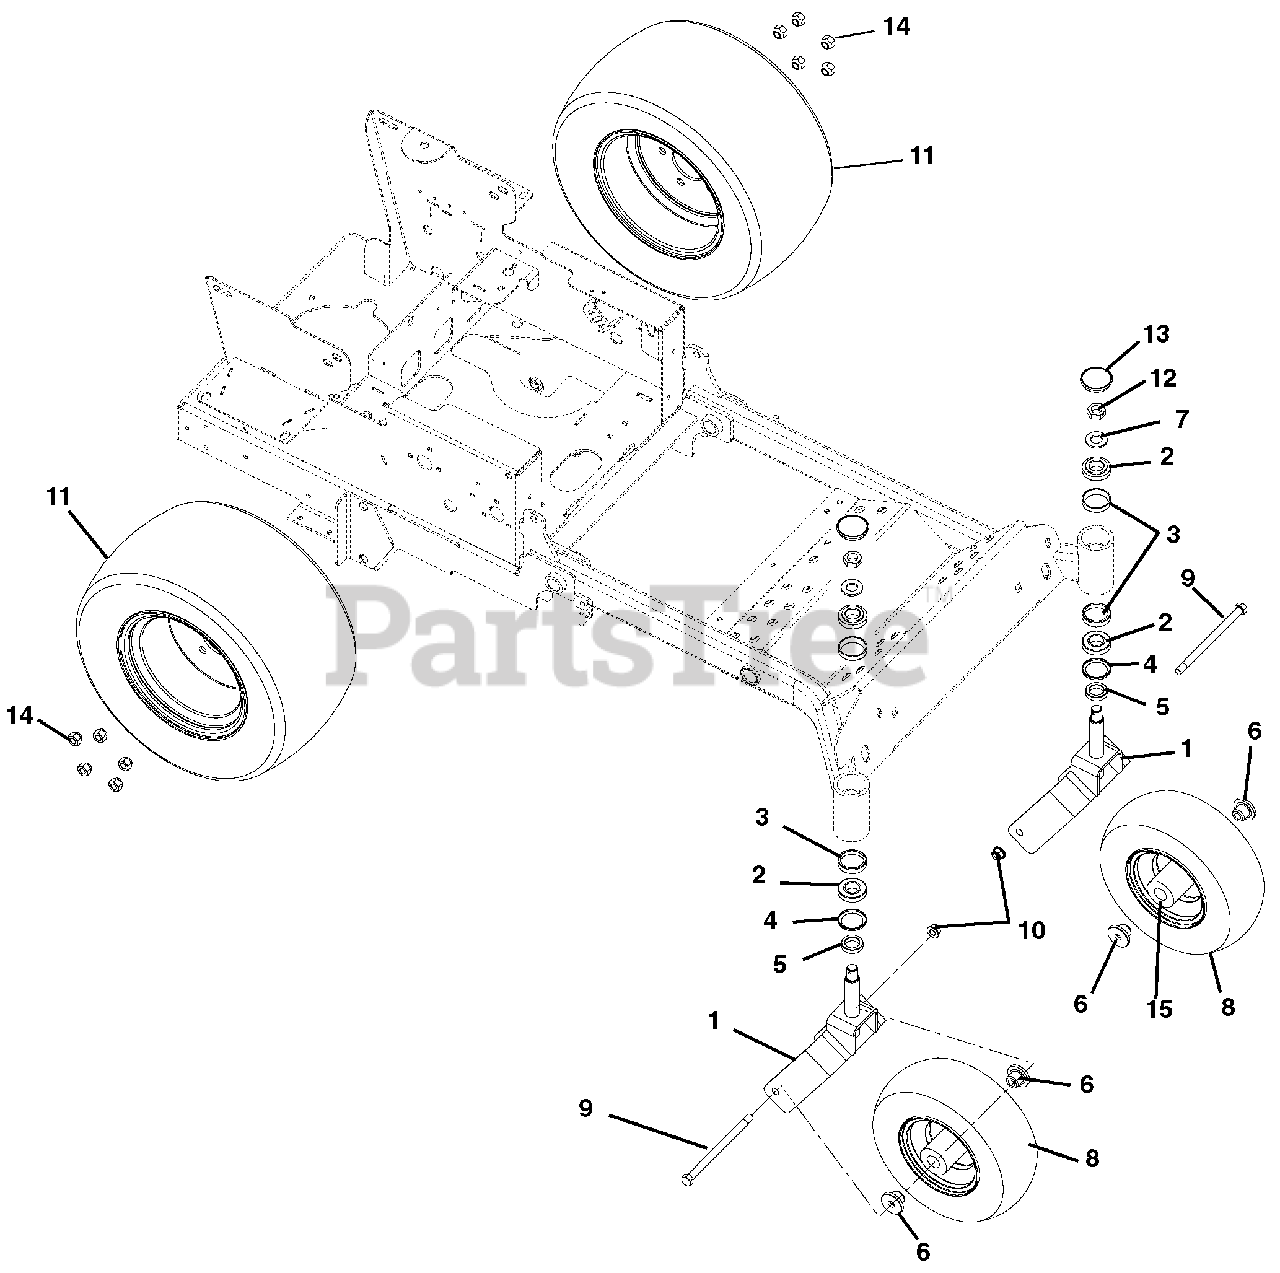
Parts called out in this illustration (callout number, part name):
1	Weldment, Front Fork
2	Bearing, Cone with Grease, 1.0 x .58
3	Bearing, Cup 1.980 x .420
4	Bearing Seal 1.5 x 2 x .18
5	Spacer, PM, 1.03 I.D. x 1.5 O.D. x .375
6	Spacer, Wheel
7	Washer, Flat-Steel .812 x 1.50 x .135
8	Tire/Wheel Assembly, 13 x 5.00-6
8	Tire/Wheel Assembly 4.80-8
9	Bolt, Hex .50-13 x 7.50 Grade 5
10	Nut, Nyloc Flange .50-13
11	Tire/Wheel Assembly, 20 x 10.00-10
11	Rim and Hub Assembly 4.10/3.50 x 6
12	Nut, Center Lock Jam .75-16
13	Cap, Dust
14	Wheel Nut .50-20
15	Bearing, 25MM ID x 52MM OD x 15MM
